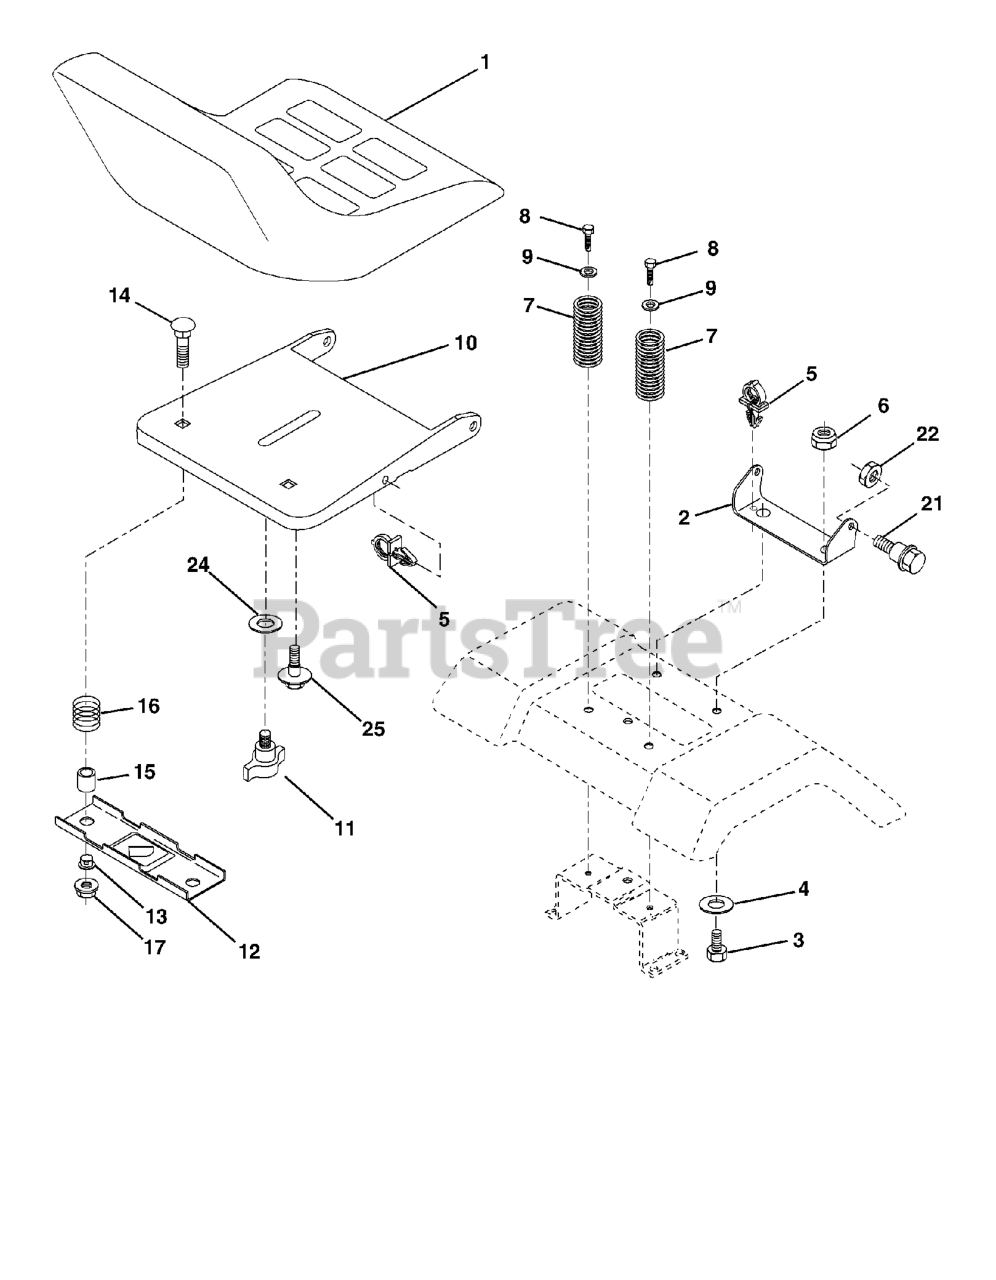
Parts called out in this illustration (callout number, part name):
1	SEAT.XH150.GRY
2	SEAT PIVOT BRKT
3	BOLT, HEX 3/8-16X1
4	WASHER PM
5	PUSH CLIP
6	NUT
7	SPRING COMPRESSION
8	SCREW 3/8-16X1
9	WASHER
10	PAN SEAT
11	KNOB.SEAT.ADJ.WINGNUT
12	BRKT SWITCH
13	BUSHING
14	BOLT.ROUND.HEAD.SQUARE.NECK
15	WASHER
16	SPRING COMPRESSED
17	NUT T
21	BOLT.SHOULDER.5/16-18
22	NUT.71038.31-18.HEX.NYLOCK
24	WASHER
25	BOLT,SHOULD
